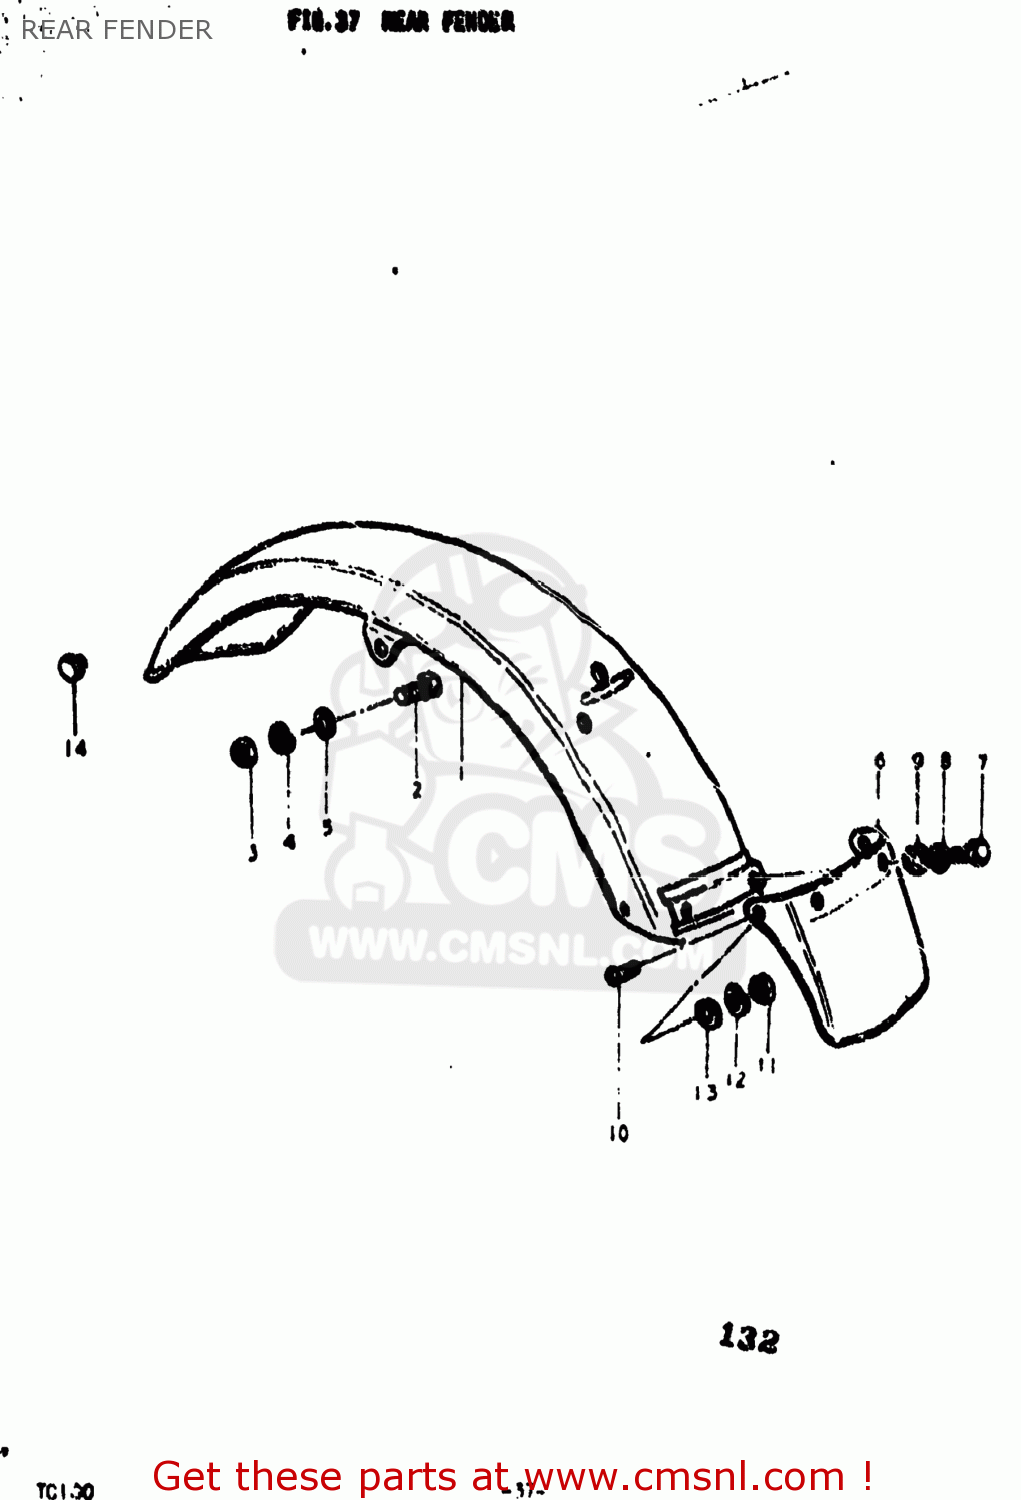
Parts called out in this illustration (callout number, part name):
1	FENDER,REAR
2	BOLT 8X40
3	NUT
4	LOCK WASHER
5	WASHER
6	MUD GUARD,REAR FENDER
7	BOLT
8	LOCK WASHER
9	WASHER
10	SCREW
11	NUT
12	LOCK WASHER
13	WASHER
14	CUSHION
